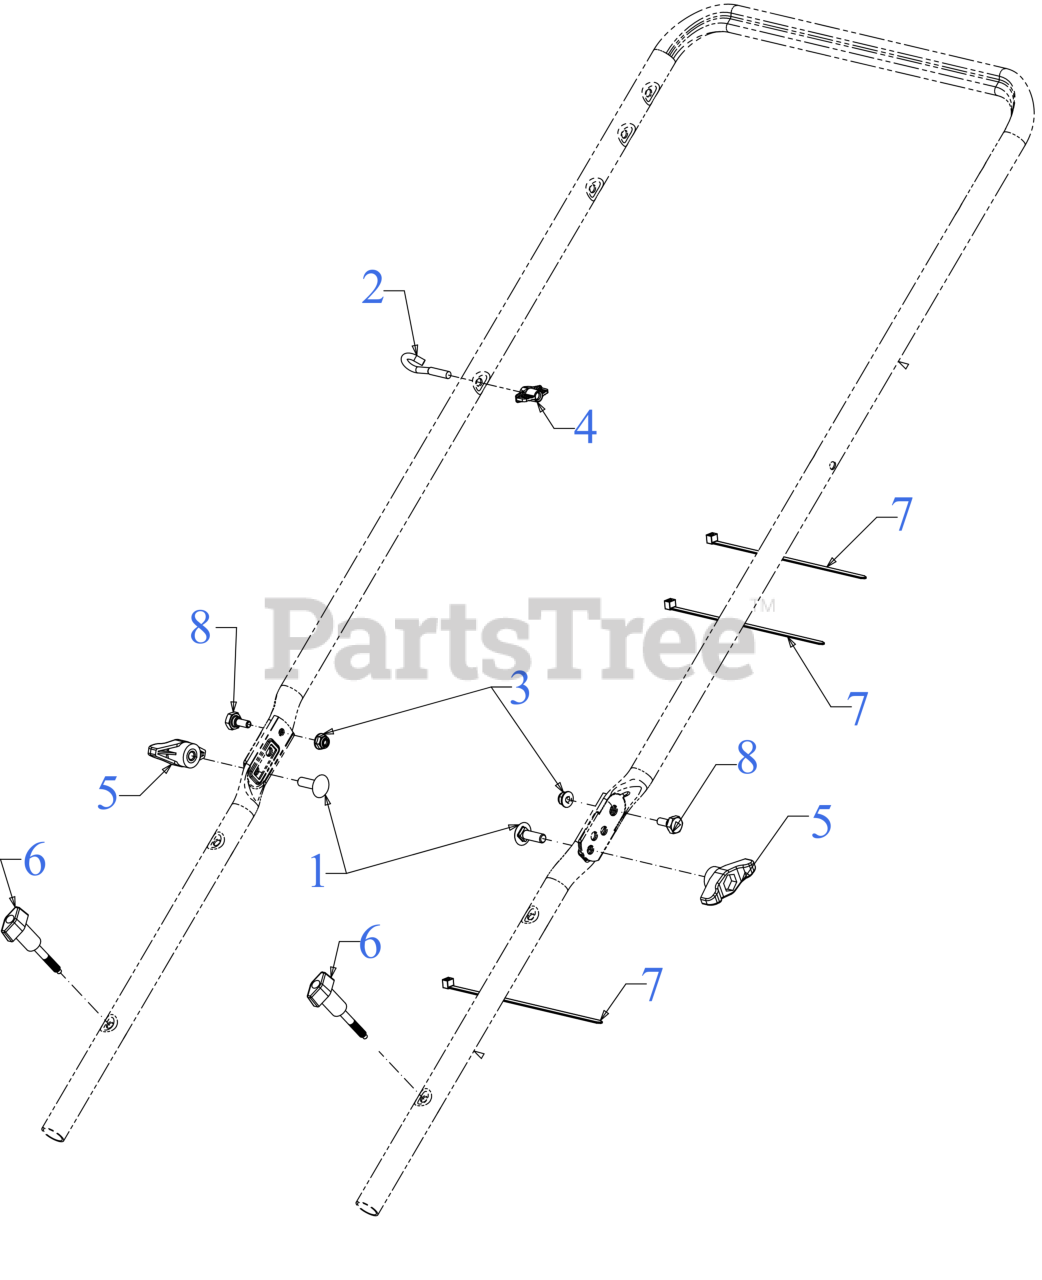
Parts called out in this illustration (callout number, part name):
1	SCREW 5/16-18 x 1.00 GR5
2	EYEBOLT 1/4-20
3	FLANGE LOCK NUT
4	HANDLE KNOB
5	WING KNOB 5/16-18
6	WING KNOB 1/4-20
7	7" CABLE TIE
8	SHOULDER SCREW
